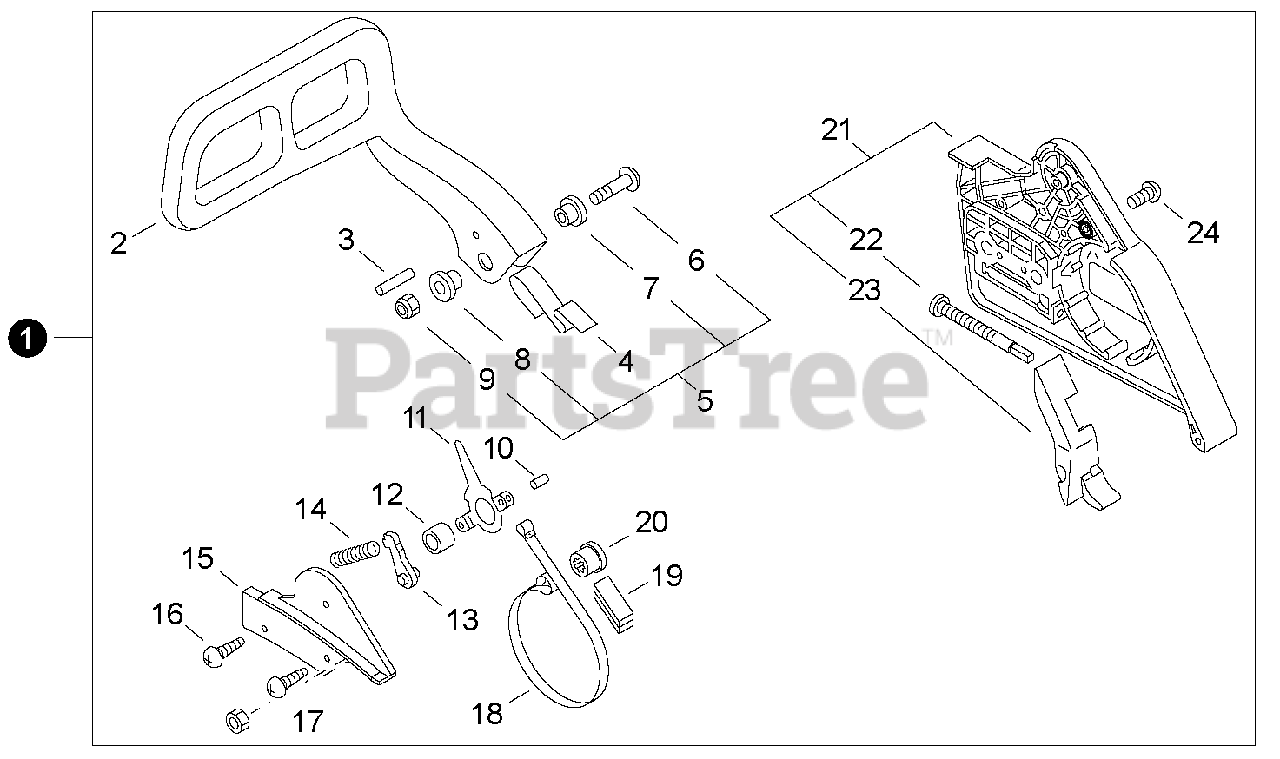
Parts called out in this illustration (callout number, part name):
1	CHAIN BRAKE ASSY
2	LEVER, BRAKE
3	PIN - 3.5X26
4	SPRING, RETURN
5	MOUNTING KIT
6	SCREW - 5X35
7	COLLAR - 5
8	SPACER - 5
9	LOCKNUT - 5
10	PIN - SPRING -- 4X8
11	LEVER, BRAKE
12	SPACER - 8
13	STOPPER, BRAKE
14	SPRING, BRAKE
15	COVER, BRAKE
16	SCREW - 4X12
18	BAND, BRAKE
20	ADJUSTER, BRAKE BAND
21	SPROCKET GUARD KIT
22	SCREW, TENSIONER
23	CUSHION
24	SCREW - 3X18
